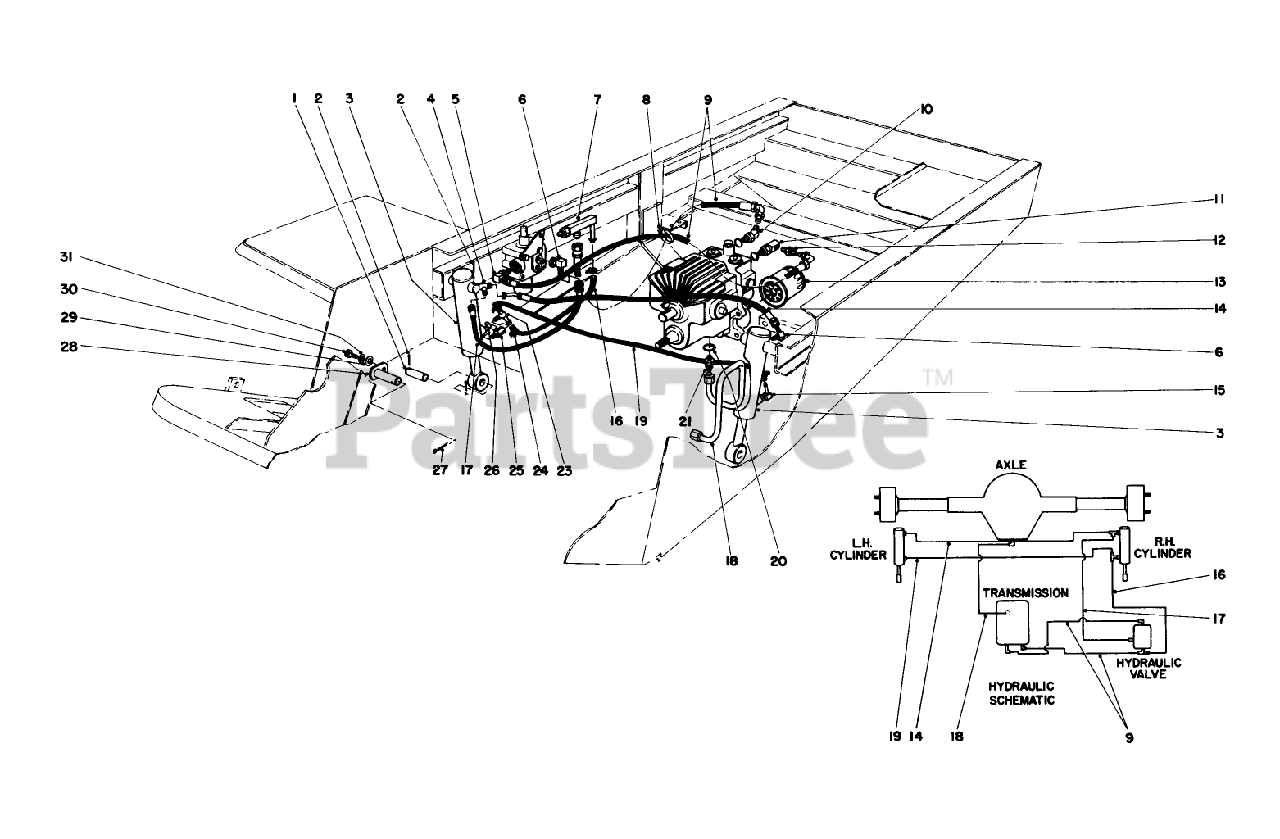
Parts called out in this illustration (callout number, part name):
1	PIN-CYLINDER
2	PIN-COTTER
3	Lift Cylinder
4	FITTING-TEE, ADJ.
5	FITTING-ELBOW, 90 DEG
6	FITTING-ELBOW, 90
7	Fitting Assembly
8	TIE-CABLE
9	TRANS-VALVE HOSE
10	FITTING-ELBOW, 45 DEG
11	SPECIAL FITTING PP
12	Adapter
13	FILTER-OIL, TRANSMISSION
14	RH CYL HOSE
15	STEM-HOSE
17	RH HOSE
18	HYORAULIC TUBE
19	HOSE-FUEL
20	O-RING
21	FITTING-STRAIGHT
23	MALE TEE FITTING
24	CLAMP-HOSE
25	CONN FITTING
26	O-RING
27	PIN-COTTER
28	Pin-Pivot
29	WASHER-FLAT
30	SCREW-HH
31	WASHER-LOCK
